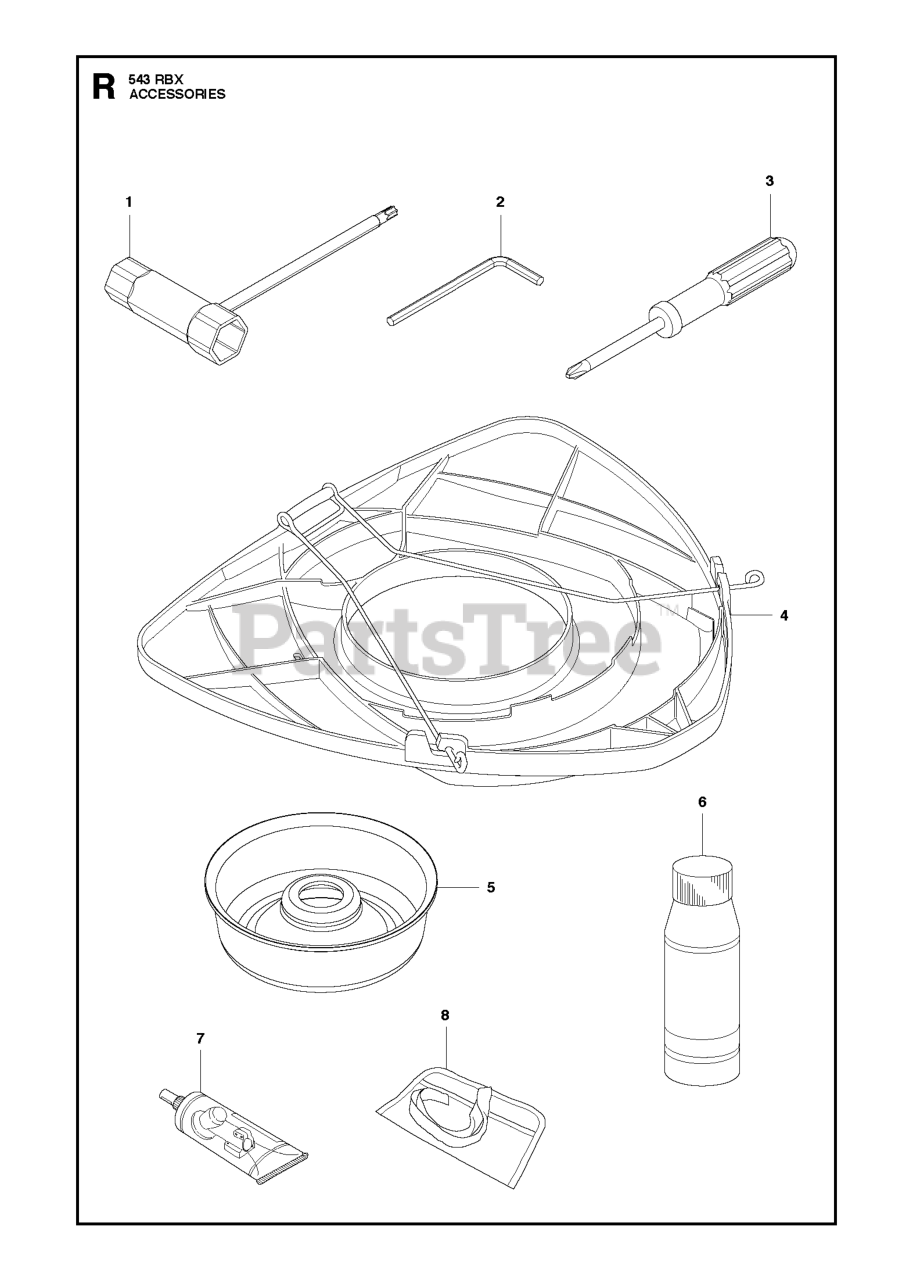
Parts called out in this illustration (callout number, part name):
3	SCREWDRIVER
4	TRANSPORT GUARD
6	Air Filter Oil 1l.
7	BEVEL GEAR GREASE
